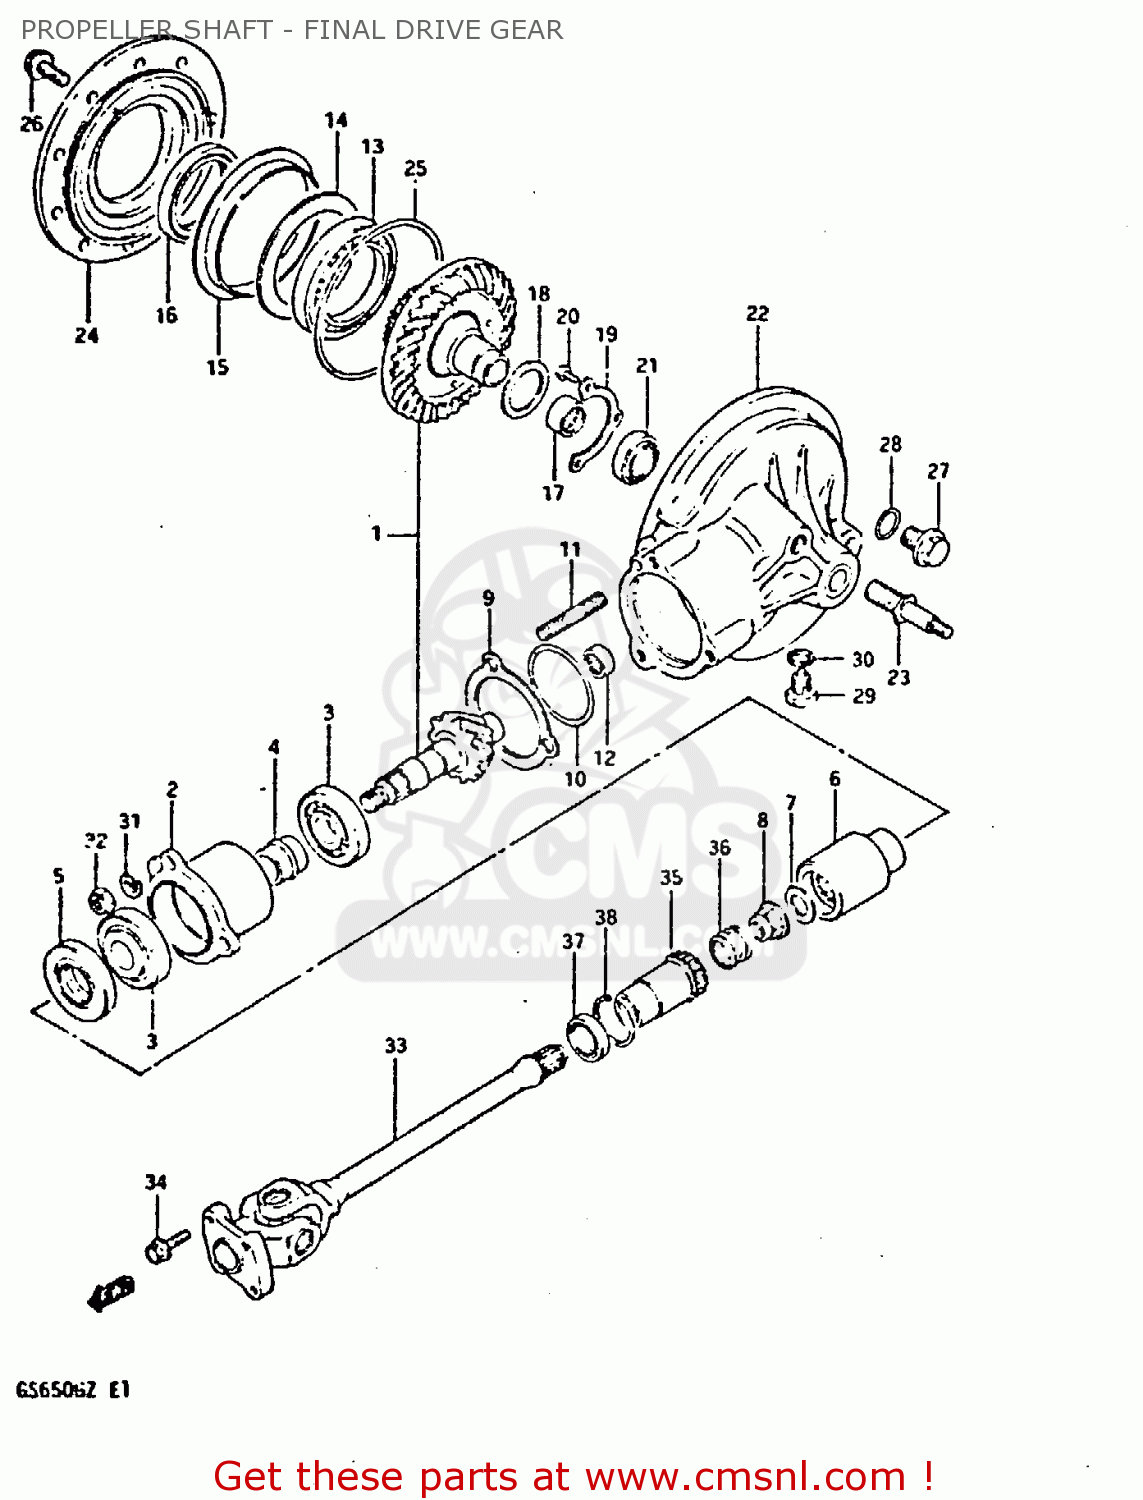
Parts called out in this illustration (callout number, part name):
1	GEAR SET,FINAL BEVEL (N
2	HOUSING,DRIVE GEAR
3	BEARING
4	SPACER
5	SEAL,OIL(32X54X7)
6	GEAR,FINAL DRIVE
7	WASHER(14X29X4)
8	NUT
9	SHIM,DRIVE GEAR HOUSING
10	O RING(D:2.4,ID:62.6)
11	STUD 10X30
12	BEARING
13	BEARING(70X110X13)
14	SHIM,DRIVEN GEAR BEARING T0.35
15	PLATE,FINAL DRIVEN BRG OIL
16	SEAL,OIL(70X96X16)
17	BEARING(32X46X17.7)
18	SHIM,FINAL DRIVEN GEAR
19	RETAINER,FINAL DRIVEN GEAR BRG
20	SCREW 6X12
21	SEAL,OIL(30X42X7)
22	CASE,FINAL GEAR
23	STUD
24	CASE,FINAL GEAR BEARING
25	O RING(D:3.5,ID:131.6)
26	BOLT
27	PLUG
28	O-RING
29	PLUG
30	GASKET(14X19.2X2) (NAS)
31	LOCK WASHER
32	NUT
33	SHAFT ASSEMBLY,PROPELLER
34	BOLT(8X17)
35	COUPLING,PROPELLER SHAFT
36	SPRING
37	SEAL,OIL(30X40.5X5.5)
38	CIRCLIP
